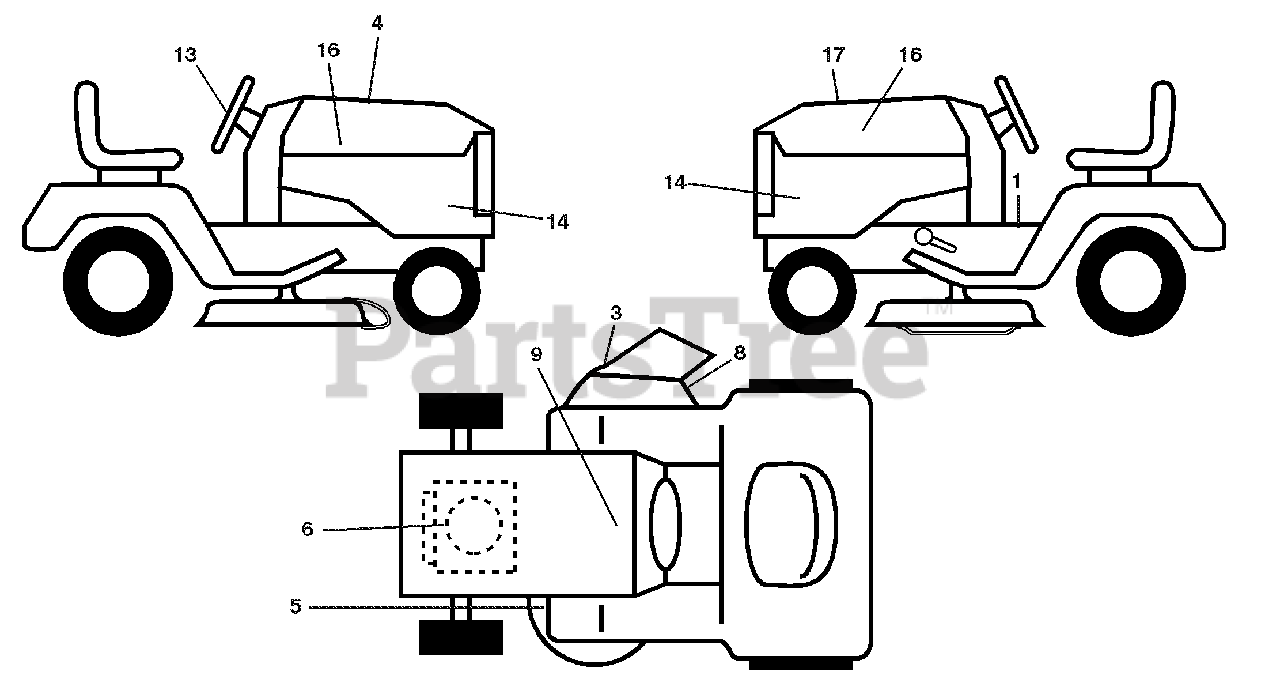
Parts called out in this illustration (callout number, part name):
1	Decal, Fender Warning
3	Decal, Warning
4	Decal, Hood Cust Resp
5	Decal, Caution
6	Decal, Eng. HP
8	Decal, Mower Sch.
9	Decal, Battery Dnge/Poi
13	Decal, Steering Whl
14	Decal, Panel Side
16	Decal, Hood Logo
17	Decal, Replacement
17	Decal, Bypass
17	Pad, Footrest, LH
17	Pad, Footrest, RH
17	Manual, Owner's
